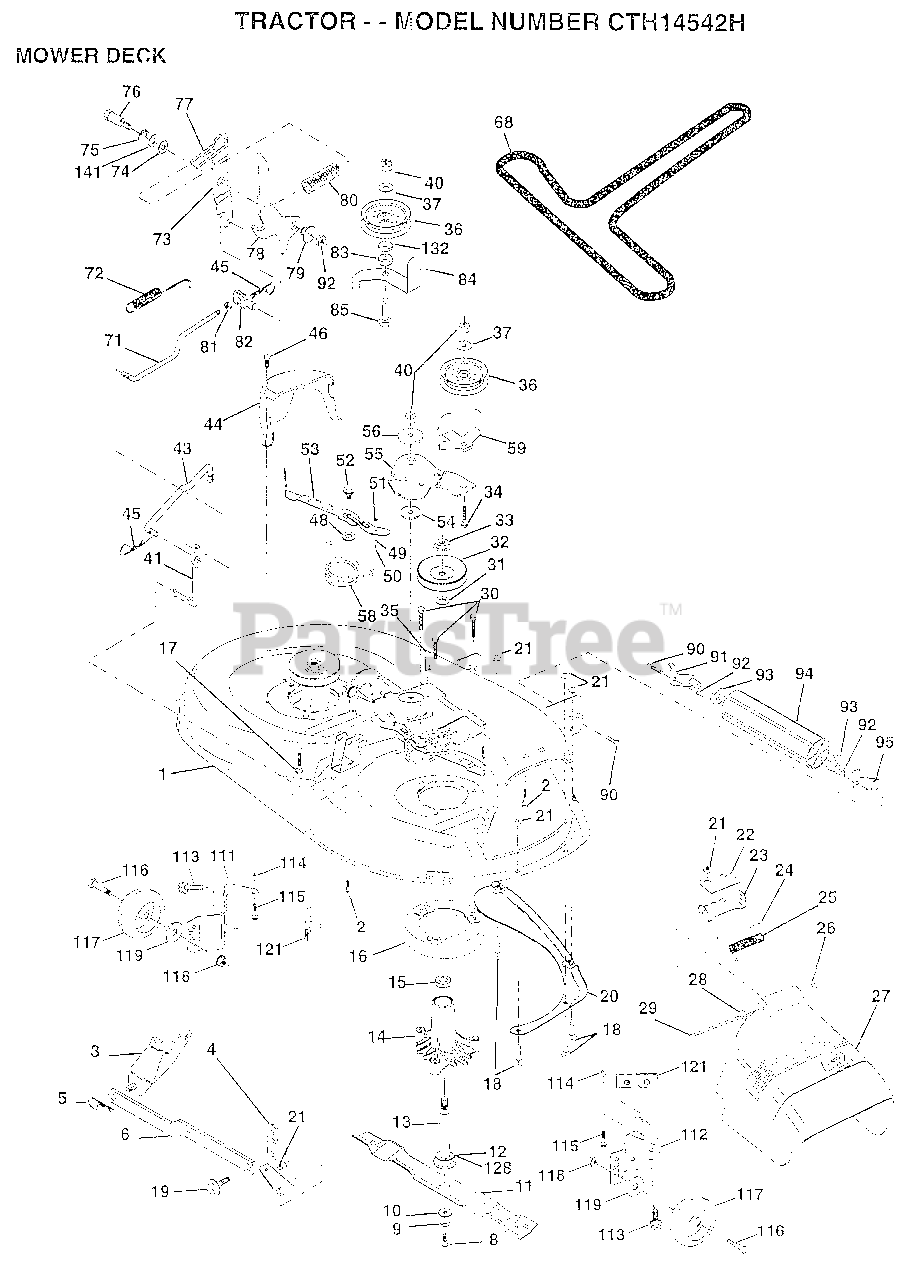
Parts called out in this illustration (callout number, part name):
1	"HOUSING ASSY.42"""
2	BOLT
3	BRKT ASM SWAY BAR
4	BRKT DECK SW BAR
8	BLADE BOLT
10	WASHER.HARD.BLADE
11	"BLADE.42"" HIPERF"
12	BEARING.BALL
14	HSG ASM MANDREL
15	BEARING
16	STRIPPER RND MWR
17	BOLT RDHD 3/8-16
18	BOLT
19	BOLT SHD 5/16-18
20	BAFFLE VORTEX 42
22	STIFFENER BRKT
23	DEFLECTOR BRKT
25	SPRING TORSION
27	DEFLECTOR.SHIELD
28	WASHER
29	HINGE ROD
30	"SCREW-THD ROLL,WA"
31	WASHER
32	PULLEY.MANDREL.42
34	BOLT
35	XMAS TREE FASTNER
36	FLAT IDLER PULLEY
37	WASHER
41	PIVOT ROD
43	ROD CLUTCH W/NIBS
44	GUARD MAND LH BLK
46	SCREW.1/4-20X5/8
48	HARD SMALL WASHER
49	ROLLER ASM-CAM
50	SHOULDER BOLT
51	LOCKNUT
52	BOLT.SHLD.5/16-18
53	BRAKE PAD ARM ASM
54	HARDENED WASHER
55	ARM-IDLER
56	SPACER RETAINER
58	SPRING TORSN BRAK
59	GUARD IDLER TUV
68	BELT.V.T-PATH
71	ROD CLUTCH 38/42
72	SPRING.EXT.RETURN
73	CLUTCH ARM SECOND
74	WASHER
75	RING
76	SHOULDER BOLT
77	SPRING KEEPER
78	ARM CLUTCH PRIMARY
79	BUSHING
80	SPRING.CLUTCH.MWR
81	NUT
82	TRUNION ADJ
83	WASHER
84	"KEEPER-BELT,FIXED"
85	BOLT
90	BOLT
92	NUT
93	WASHER
111	BRACKET.GWHL.LH.
112	BRACKET.GWHL.RH.
113	SCREW
116	BOLT.SHOULDER
117	WHEEL.GUAGE.MED.
118	LOCKNUT
119	WASHER
121	BRACKET.EXTRD.GWL
128	WASHER.FELT.
132	WASHER GT
141	WASHER .T
